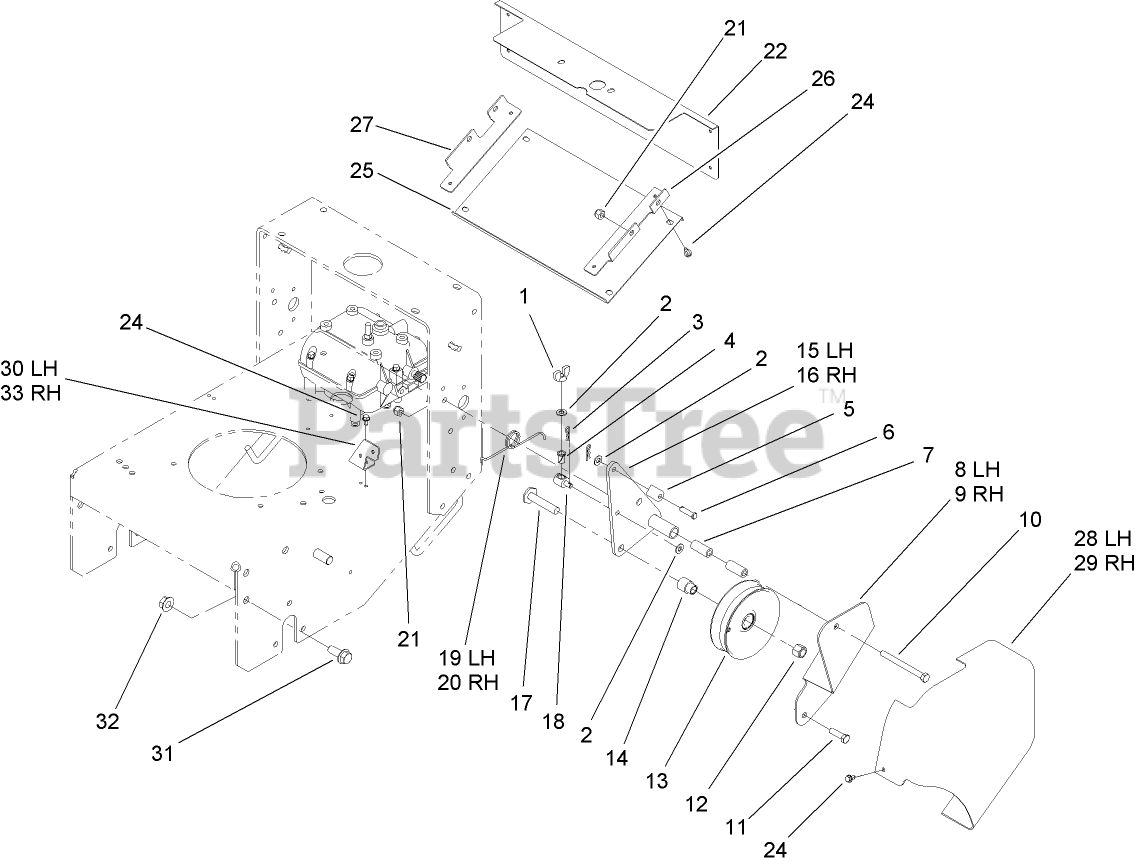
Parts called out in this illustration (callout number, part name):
1	NUT-WING
2	WASHER-PLAIN
3	PIN-COTTER
4	BUSHING-NYLON
5	FITTING-ROD
6	PIN-CLEVIS
7	SPACER-PIVOT, IDLER
8	SUPPORT-IDLER, LH
9	SUPPORT-IDLER, RH
10	SCREW-HH
11	SCREW-HH
12	NUT-LOCK, NI
13	PULLEY-IDLER
14	SPACER-PULLEY
15	ARM-IDLER, LH
16	ARM-IDLER, RH
17	SCREW-LEVELER
18	FITTING-ROD
19	SPRING-TORSION, LH
20	SPRING-TORSION, RH
21	NUT-LOCK, NI
22	GUARD-SHAFT, TRANSMISSION
24	SCREW
25	PANEL-BOTTOM
26	ANGLE-MOUNTING, LEFT
27	ANGLE-MOUNTING, RIGHT
28	GUARD-BELT, LH
29	GUARD-BELT, RH
30	BRACKET-MOUNTING, LH
31	SCREW-HHF
32	NUT-HF
33	BRACKET-MOUNTING, RH
